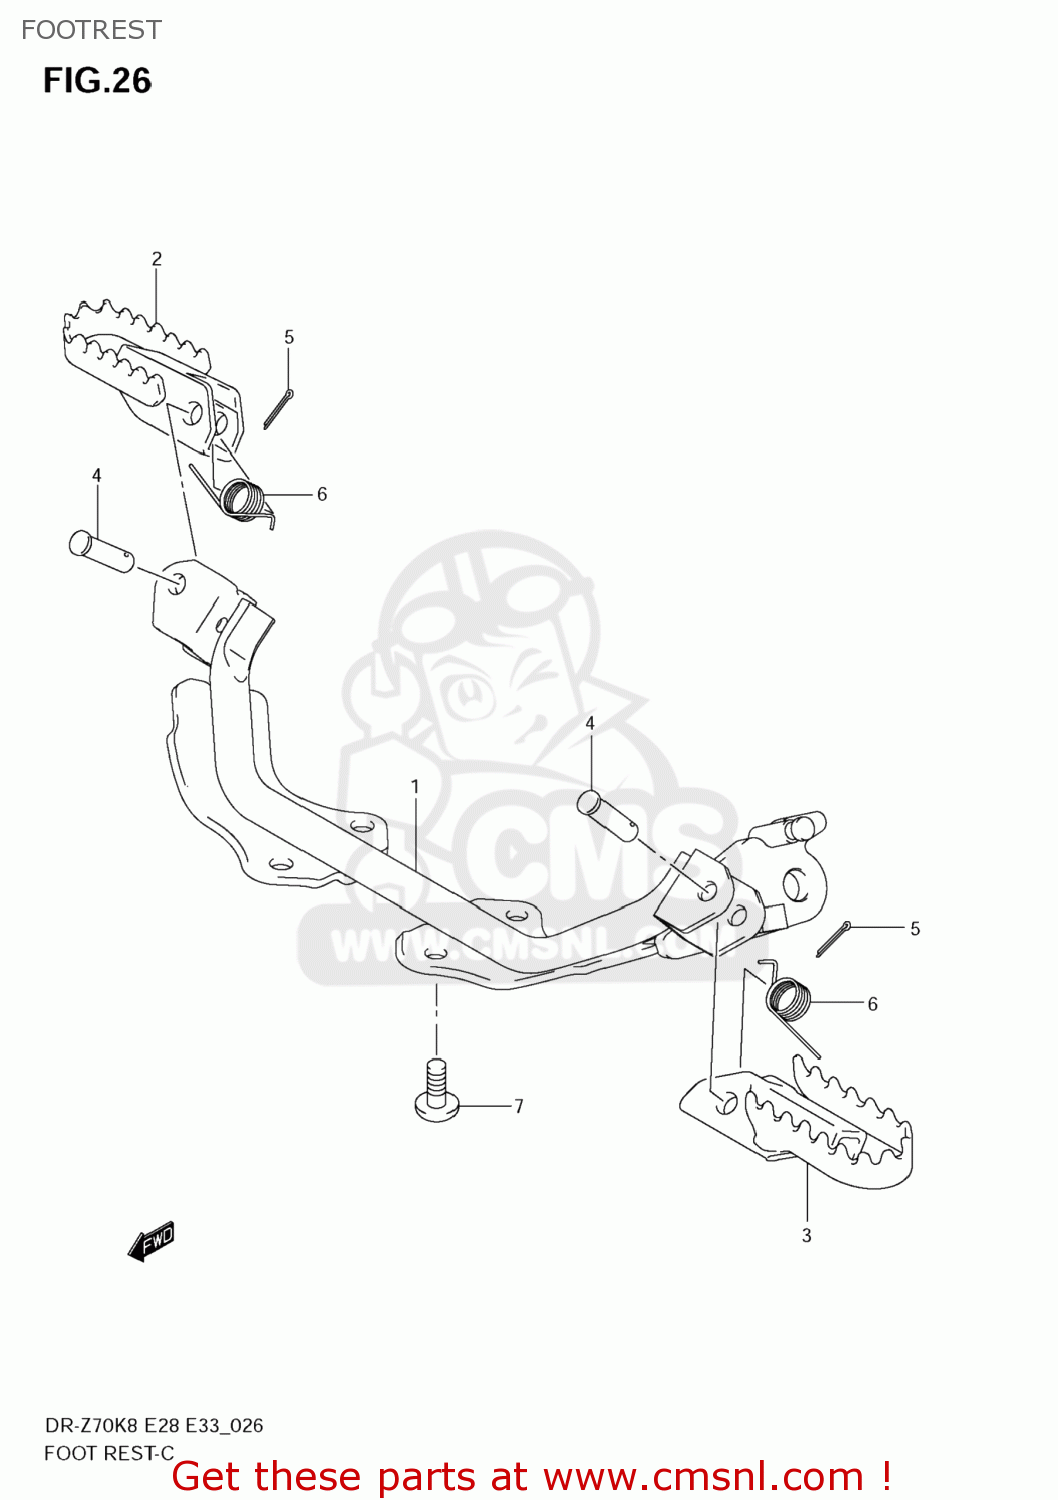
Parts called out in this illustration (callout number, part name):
1	BAR,FR FOOTREST
2	FOOTREST,FR,R
3	FOOTREST,FR,L
4	PIN
5	PIN
6	SPRING
7	BOLT(8X16)
